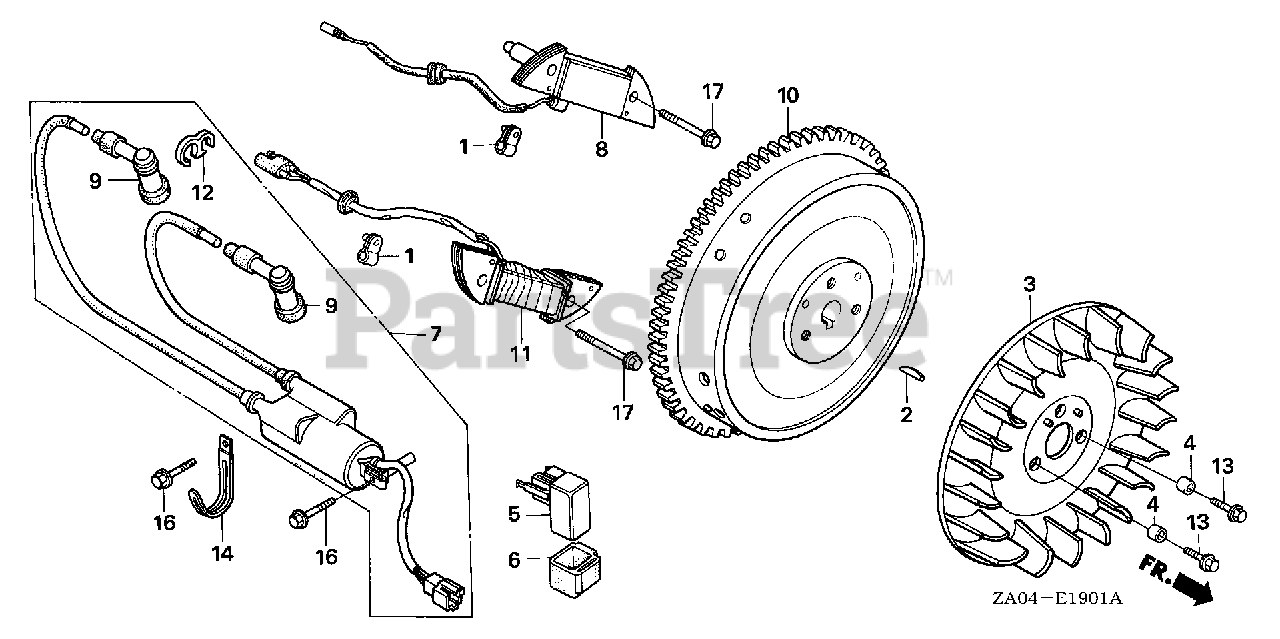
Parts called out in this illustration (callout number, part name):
1	CLAMP, CHARGE COIL (NOT AVAILABLE)
2	KEY, SPECIAL WOODRUFF (25X18)
3	FAN, COOLING
4	COLLAR, FAN
5	MODULE, IGNITION CONTROL (CDI)
6	CUSHION, IGNITION CONTROL MODULE (CDI)
7	COIL ASSY., C.D.I. IGNITION (NOT AVAILABLE)
8	COIL ASSY., EXCITER (NOT AVAILABLE)
9	CAP ASSY., NOISE SUPPRESSOR
10	FLYWHEEL (NOT AVAILABLE)
11	COIL ASSY., CHARGING (NOT AVAILABLE)
12	CLAMP A, TUBE
13	BOLT, FLANGE (6X16)
14	CLIP (2X50)
16	BOLT, FLANGE (6X45)
17	BOLT, FLANGE (6X50)
